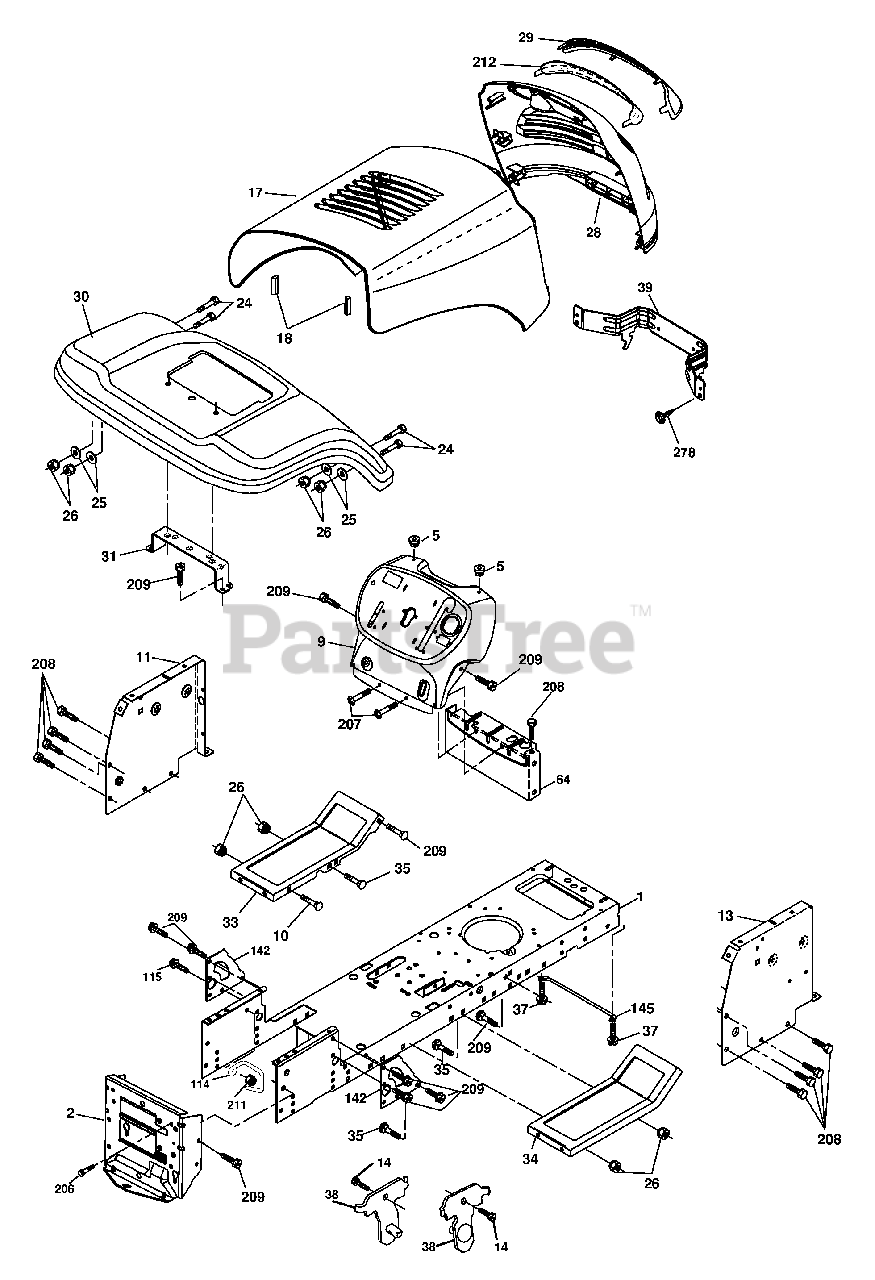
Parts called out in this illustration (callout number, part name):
1	Chassis Stamping
2	Drawbar
5	Bumper Hood/Dash
9	Dash
10	Bolt, Carriage 3/8-16 x 1
11	Panel, Dash, L.H.
13	Panel, Dash, R.H.
14	Screw Thdrol 3/8-16 x 1/2
17	Hood Assembly
18	Bumper Hood Large 1.75
24	Bolt Fin Hex 3/8-16 unc x 1 Gr. 5
25	Washer 13/32 x 13/16 x 12 Ga.
26	Nut
28	Grille Lens Asm Laser
29	Lens
31	Bracket, Fender Support
33	Footrest LH
34	Footrest RH
35	Bolt Rdhd Sht Sqnk 3/8-16 x 3/4
37	Screw Thdrol 5/16-18 x 1/2 Tyt
38	Bracket Asm. Pivot Mower Rear
39	Bracket Pivot
64	Dash Lower
114	Keeper Belt Rear LH
115	Screw 3/8-16 x 1-1/4
142	Plate Reinforcement
145	Rod Pivot Chassis/Hood
206	Bolt Shoulder 5/16 -18 TT
207	Screw 5/16-18 x 1/2
208	Screw Thdrol 3/8-16 x 1/2
209	Screw Hex Wsh Thdr 3/8-16 x 3/4
211	Nut Hex Flange Lock
212	Insert Lens Reflective
278	Screw 10 x 3/4 Single Head-Hex
